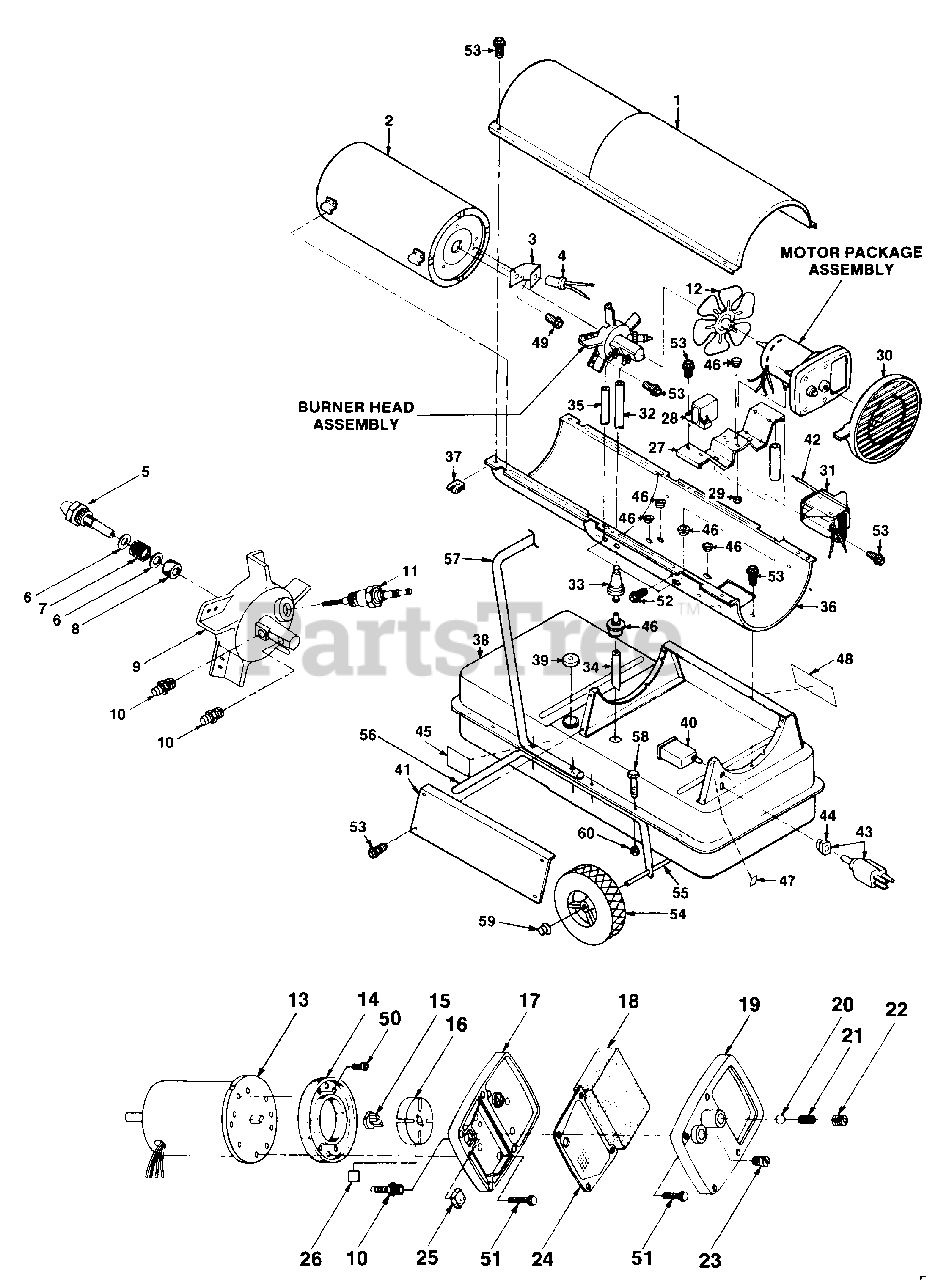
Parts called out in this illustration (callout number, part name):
1	UPPER SHELL
2	CHAMBER- Combustion
3	PHOTOCELL BRACKET
4	PHOTOCELL ASSEMBLY
6	WASHER- Nozzle
7	SPRING- Nozzle
8	SLEEVE- Nozzle
9	BODY- Burner head
10	FITTING- Barb.
11	SPARK PLUG
12	FAN
13	MOTOR (Split phase)
14	PUMP- Body
15	INSERT- Rotor
16	ROTOR- Pump
17	COVER- End pump
18	FILTER- Intake
19	COVER- End filter
20	BALL- Steel 1/4 dia.
21	SPRING- Relief
22	SCREW- Adjusting
24	FILTER- Output
25	FILTER- Lint
27	BRACKET- Motor Mounting
28	SOLID STATE RELAY
29	NUT- Lock hex
30	GUARD- Fan
32	FUEL LINE
33	FILTER- Fuel
34	FUEL LINE TUBE
36	SHELL- Lower
37	CLIP- Nut
38	TANK- Fuel
39	CAP- Fuel (includes gasket)
40	CONTROL- Safety
41	COVER- Side
42	IGNITOR CABLE ASSY.
43	POWER CORD ASSY.
44	BUSHING- Strain Relief
45	DECAL- Fuel
46	RUBBER BUSHING & BUMPER KIT
47	DECAL- Reset
48	DECAL- General Info.
56	FRAME SUPPORT WHEEL
57	FRONT HANDLE
58	MOUNTING SCREWS
60	NUT- Hex Lock #10-24
